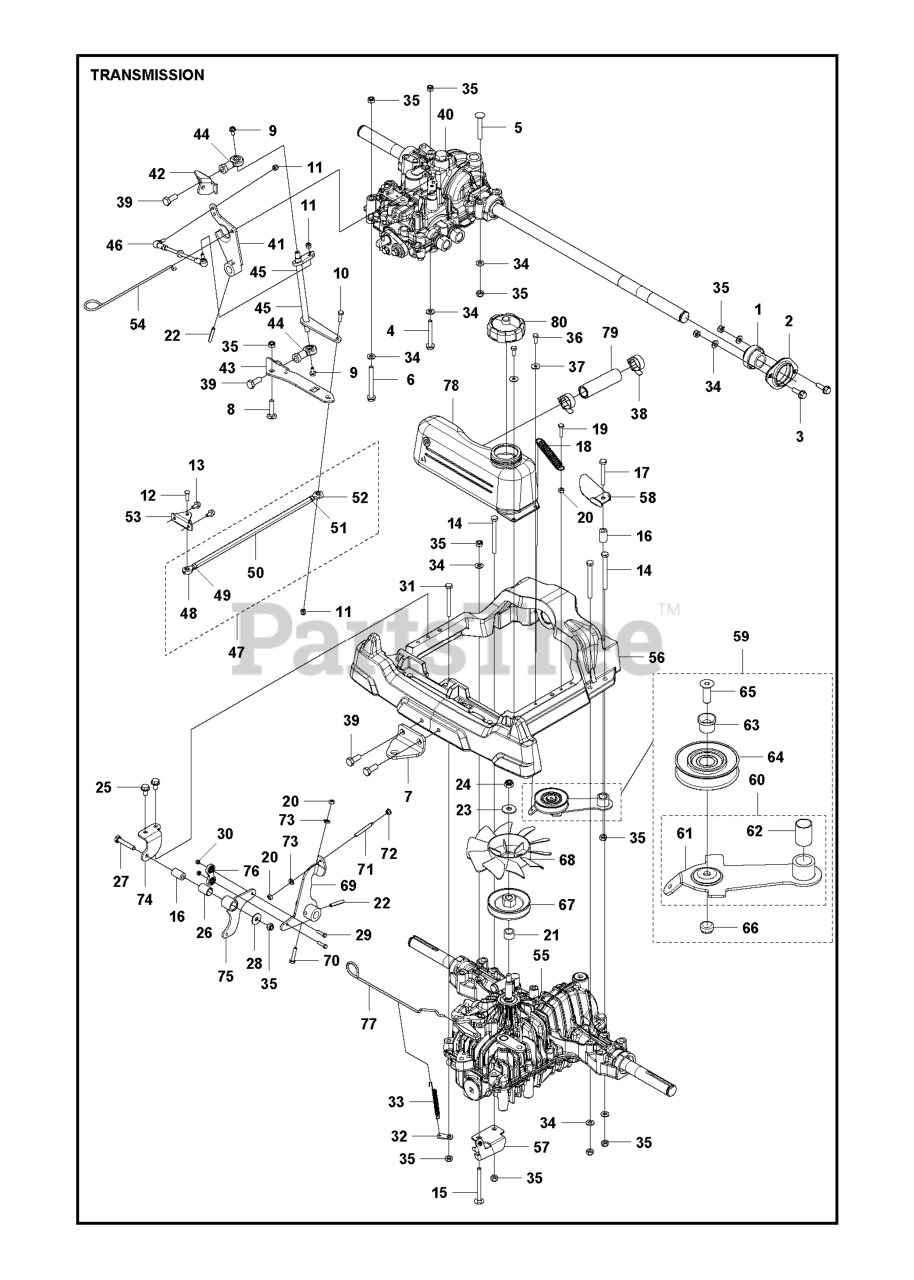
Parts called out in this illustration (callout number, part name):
2	BEARING HOUSING
3	BOLT
8	Screw Mvbf 8 X 40
9	SCREW EHHFM
11	NUT FLANGE - M6
24	NUT
27	SCREW
29	SCREW M6S 5X20
30	LOCKNUT M5
34	WASHER BRB 8.4X17
35	LOCKNUT M8
36	BOLT FLANGE - M6X20
37	WASHER - 26X6.5X1.6
39	Screw M10x25
47	ROD
61	TENSIONER
66	LOCKNUT M8
70	SCREW M6S 6X30
78	EXPANSION TANK K664
